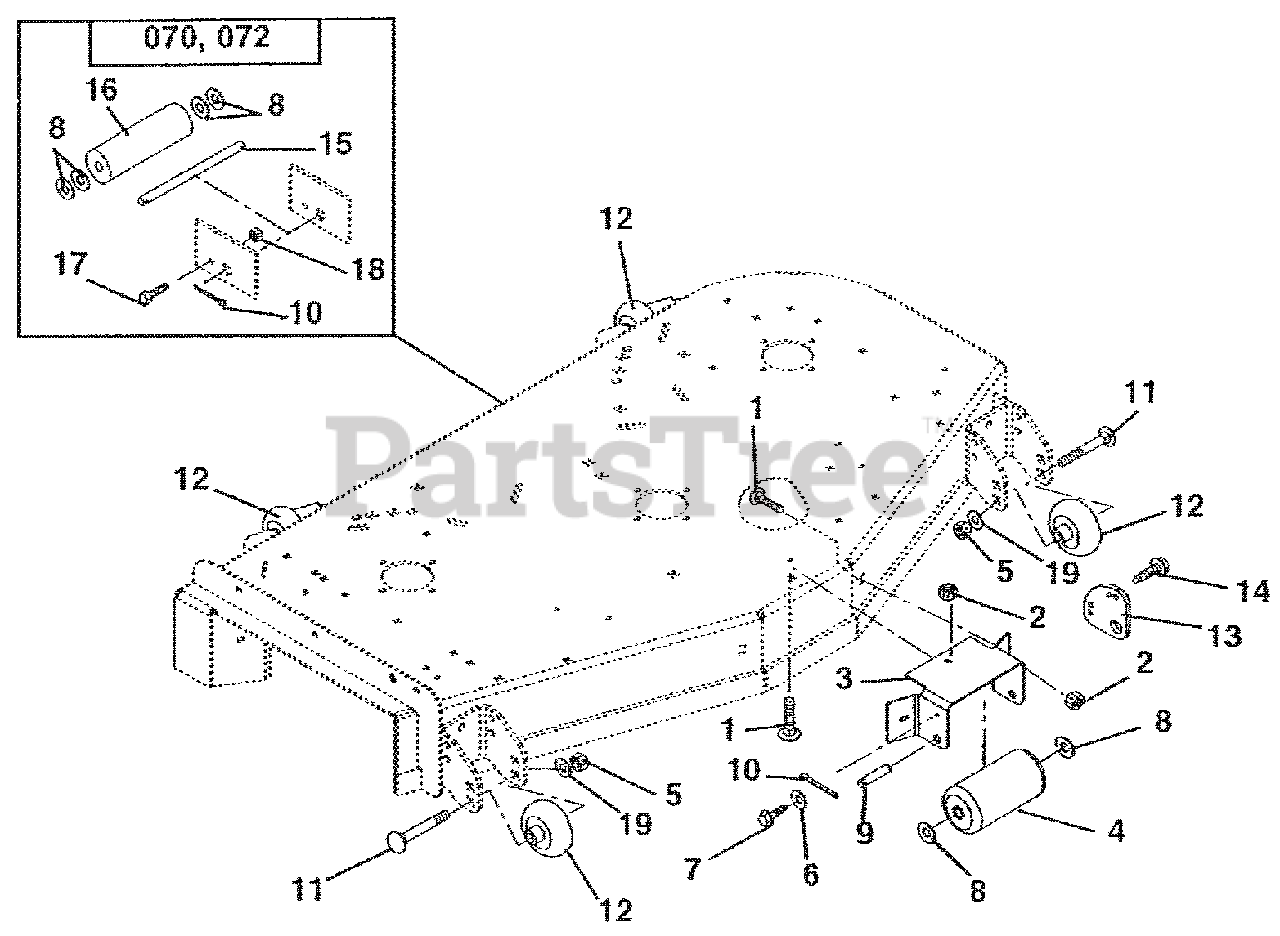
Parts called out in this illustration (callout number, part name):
1	Bolt-Round Head Square Neck .38-16 x 1.00 Grade 5
2	Nut-Locking-Top-Flange .38-16
3	Bracket-Anti-Scalp Roller
5	Nut-Locking-Nylon .50-13
6	Washer-Flat-Steel .281 x .62 x .065
7	Scew-Tapping .25-20 x .75 Hex Washer Head
8	Washer-Flat-Steel .656 x 1.31 x .095 (066, 067, 068, 069, 071)
9	Pin-Roll .250 x 1.25 Stainless Steel
10	Pin-Cotter .25 x 2.00 (066, 067, 068, 069)
11	Bolt-Round Head Square Neck .50-13 x 5.00 Grade 2
12	Wheel, 3 x 5
13	Anti-Scalp Washer
14	Screw-Tapping .25-20 x .62 Hex Washer Head
15	Shift, Center Roller (070, 072)
16	Roller, Gage (070, 072)
17	Bolt-Hex .25-20 x .75 Grade 5 (070, 072)
18	Nut-Locking-Center .25-20 (070, 072)
19	Washer-Flat-Steel .531 x 1.06 x .095
